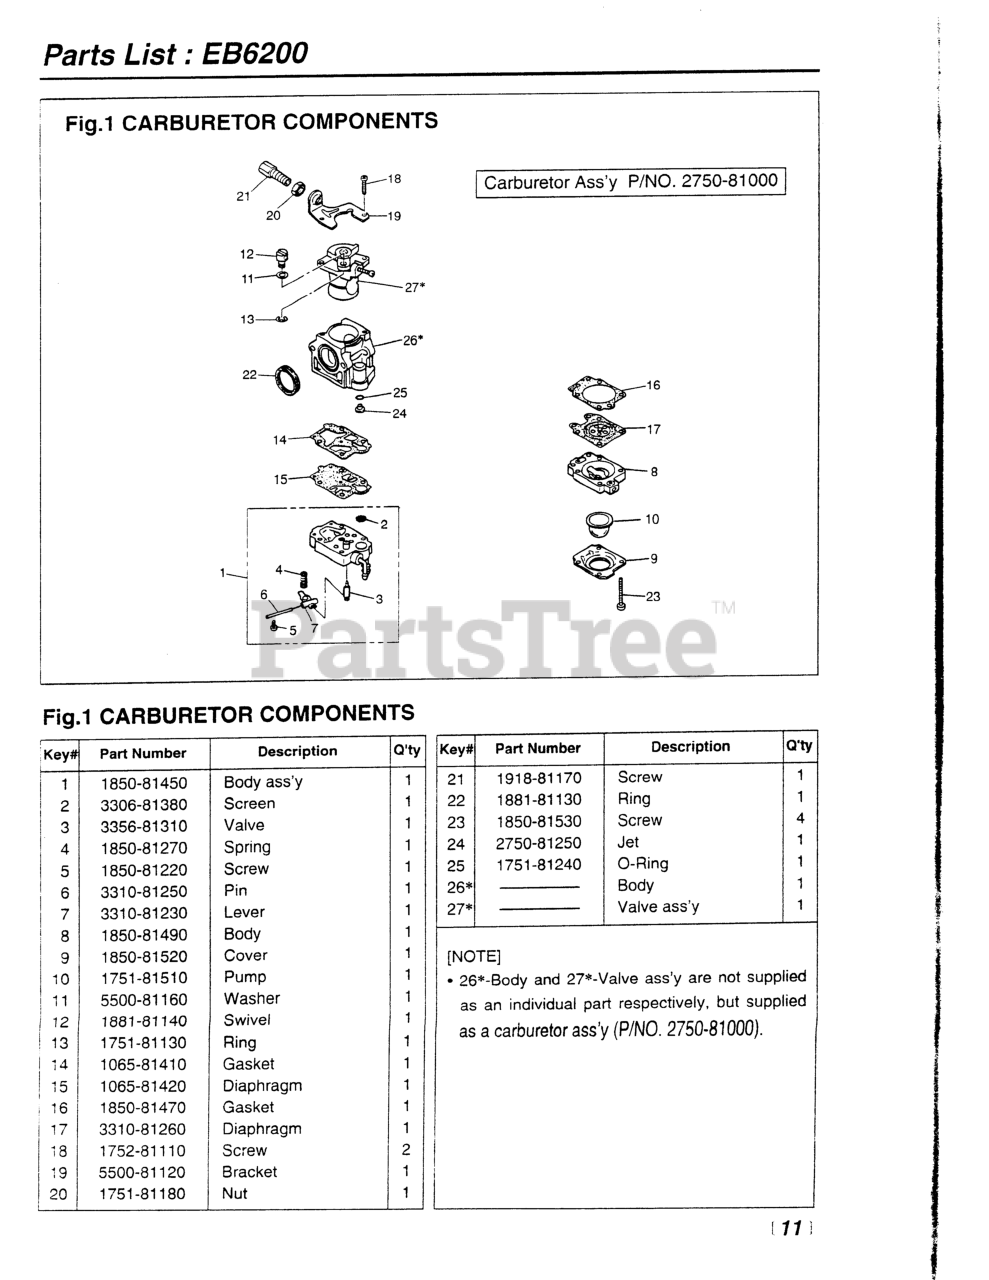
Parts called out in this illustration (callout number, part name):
1	BODY, PUMP
3	VALVE, INLET
4	SPRING, METERING LEVER
5	SCREW, METERING LEVER PIN
6	PIN, METERING LEVER
7	LEVER
8	BODY, PURGE
9	COVER, PUMP
10	PUMP, PRIMING
11	WASHER
12	SWIVEL
13	RING
14	GASKET, PUMP
15	DIAPHRAGM
16	GASKET, DIAPHRAGM
17	DIAPHRAGM (USE 4810-81260)
18	SCREW
20	NUT, CABLE ADJUSTER
21	SCREW, CABLE ADJUSTER
22	RING, PACKING
23	SCREW
24	JET
25	RING, O
26	CARBURETOR (WYK-73-1)
27	CARBURETOR (WYK-73-1)
